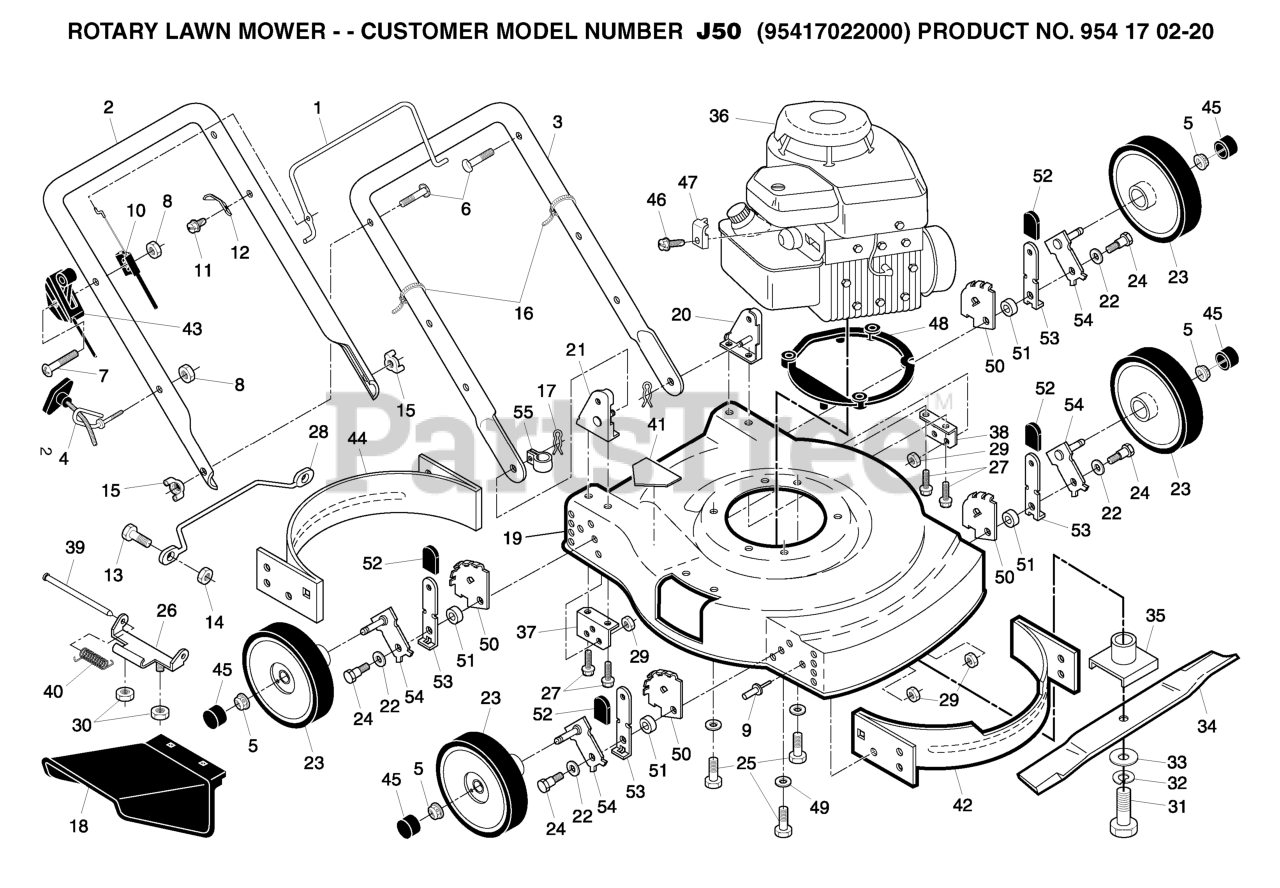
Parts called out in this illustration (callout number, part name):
1	BAIL.CONT.D.STRAIGHT.PUSH.BLK
3	HANDLE
4	ROPE, GUIDE
5	HEX FLANGE LOCKNT
6	BOLT, HANDLE 5/16-18X1.75
8	NUT
9	RIVET BLIND
10	CABLE.MZR.51.RT.SP./PU.
12	BRACKET UPSTOP
13	REPL BY 817 02 10-08
15	NUT WING PM
16	TIE GUIDE
17	HAIRPIN COTTER
20	HANDLE BRACKET ASM. LH
21	HANDLE BRACKET ASM. RH
22	WASHER.BELLEVILLE (3 2 LB)
23	WHEEL
24	BOLT
26	BRACKET PM
27	SCREW.5/16-18X3/4
29	LOCKNUT PM
30	LOCKNUT.NYLOC.1/4-20
31	SCREW, HEX HD 3/8-24 X 1-3/8
32	LOCKWASHER
33	WASHER,HARDEN
34	20" Blade
35	BLADE ADAPTOR
39	ROD.HINGE.COMBI-C
41	DECAL.INTERNATIONL.CUTFINGER
46	SCREW.HEX.HEAD.WASHER.10-16
47	CABLE CLAMP(ENGINE)
50	WHEEL ADJUST BRACKET
51	RP SPACER HT ADJ
53	SELECTOR SPRING
54	AXLE, REAR
55	CLIP.CABLE.BLK
